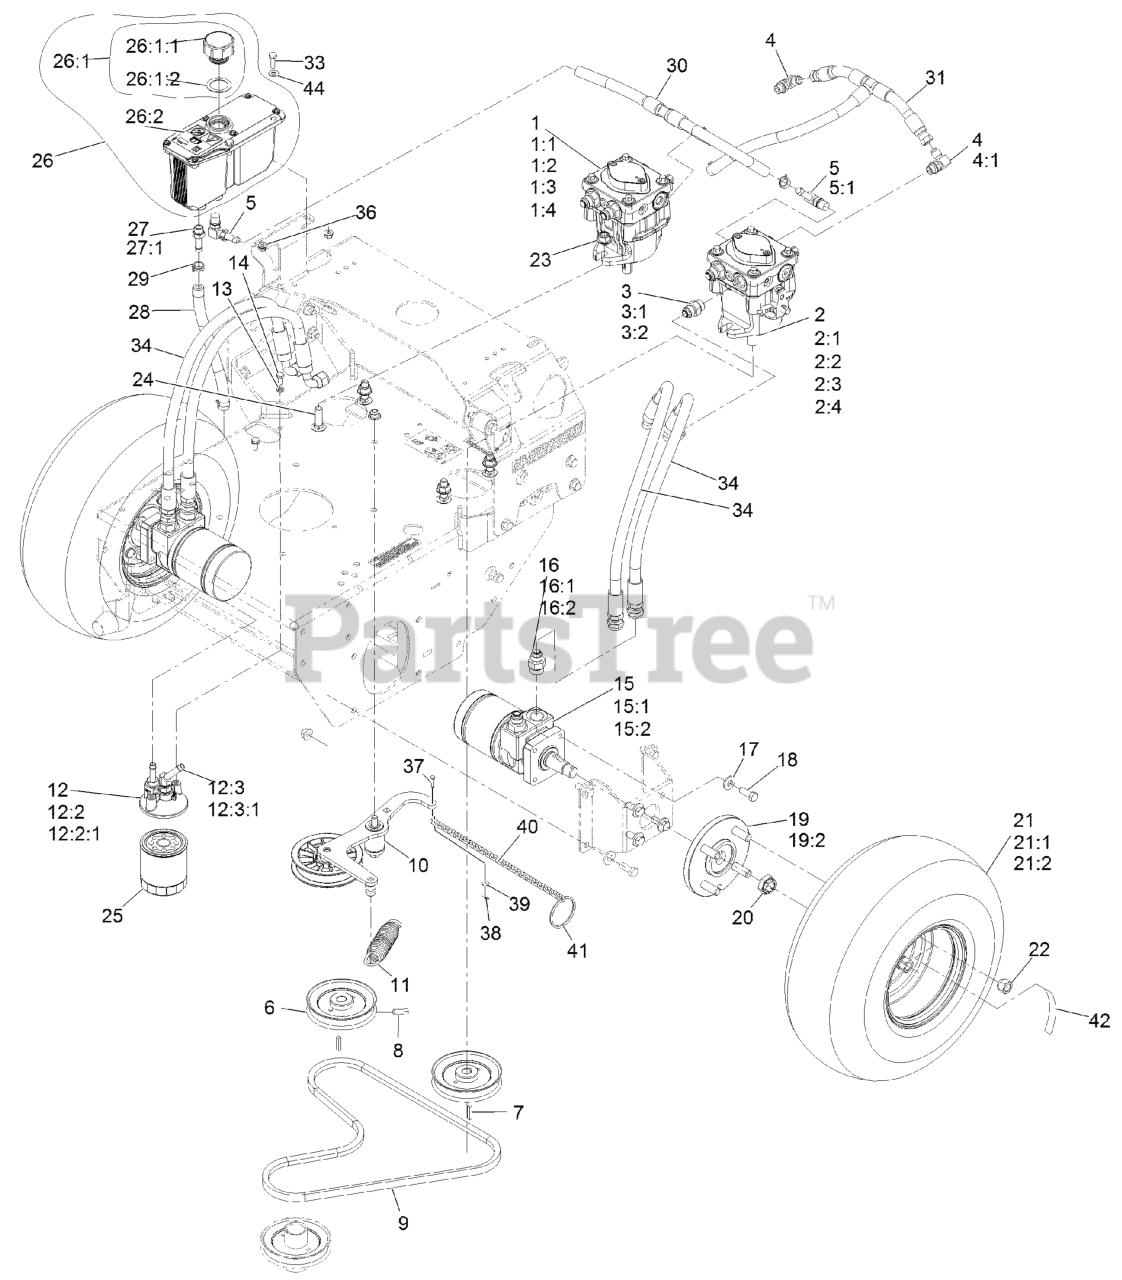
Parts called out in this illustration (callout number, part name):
1	RH HYD PUMP ASM
1:1	INPUT SHAFT KIT
1:2	BEARING-THRUST
1:3	CYLINDER BLOCK KIT
1:4	SEAL OVERHAUL KIT
2	LH HYD PUMP ASM
2:1	INPUT SHAFT KIT
2:2	BEARING-THRUST
2:3	CYLINDER BLOCK KIT
2:4	SEAL OVERHAUL KIT
3	FITTING-STRAIGHT
4	FITTING-ELBOW, 90 DEG
4:1	O-RING
5	FITTING-ELBOW, 90
5:1	O-RING
6	SHEAVE ASM
8	SCREW-SET, SQH
9	BELT
10	ASM, PUMP IDLER
11	SPRING-EXTENSION
12	ASM, FILTER HEAD
12:2	ADAPTER-STRAIGHT
12:2:1	O-RING
12:3	FITTING-BARBED, 45 DEG
12:3:1	O-RING
13	WASHER-LOCK
14	SCREW-HH
15	HYD MOTOR ASM
15:1	SEAL KIT
15:2	BEARING AND SEAL KIT
16	FITTING-STRAIGHT
16:1	O-RING
17	WASHER-BELLEVILLE
18	SCREW-HH
19	WHEEL HUB ASM
19:2	STUD-WHEEL
20	NUT-LOCK
21	WHEEL AND TIRE ASM
21:1	TIRE-TURFMASTER
21:2	RIM-WHEEL
22	NUT-LUG
23	NUT-HF, NI
24	BOLT-CARR
25	FILTER-25 MICRON, BI-DIRECTIONAL
26:1	Reservoir-HYD
26:1:1	Cap-Reservoir, HYD
26:1:2	GASKET-CAP
26:2	DECAL-WARNING
27	ADAPTER-STRAIGHT
27:1	O-RING
28	HOSE-CHARGE
29	CLAMP-HOSE
30	HOSE-CASE DRAIN
31	HOSE-CHARGE
33	SCREW-HH
34	HYD HOSE ASM
36	NUT-HHF
37	PIN-CLEVIS
38	PIN-HAIR
39	WASHER-PLAIN
40	CHAIN-LINK, TWIST
41	RING-SPLIT
42	DECAL-TORQUE WHEEL LUG-HU
44	WASHER-FLAT
